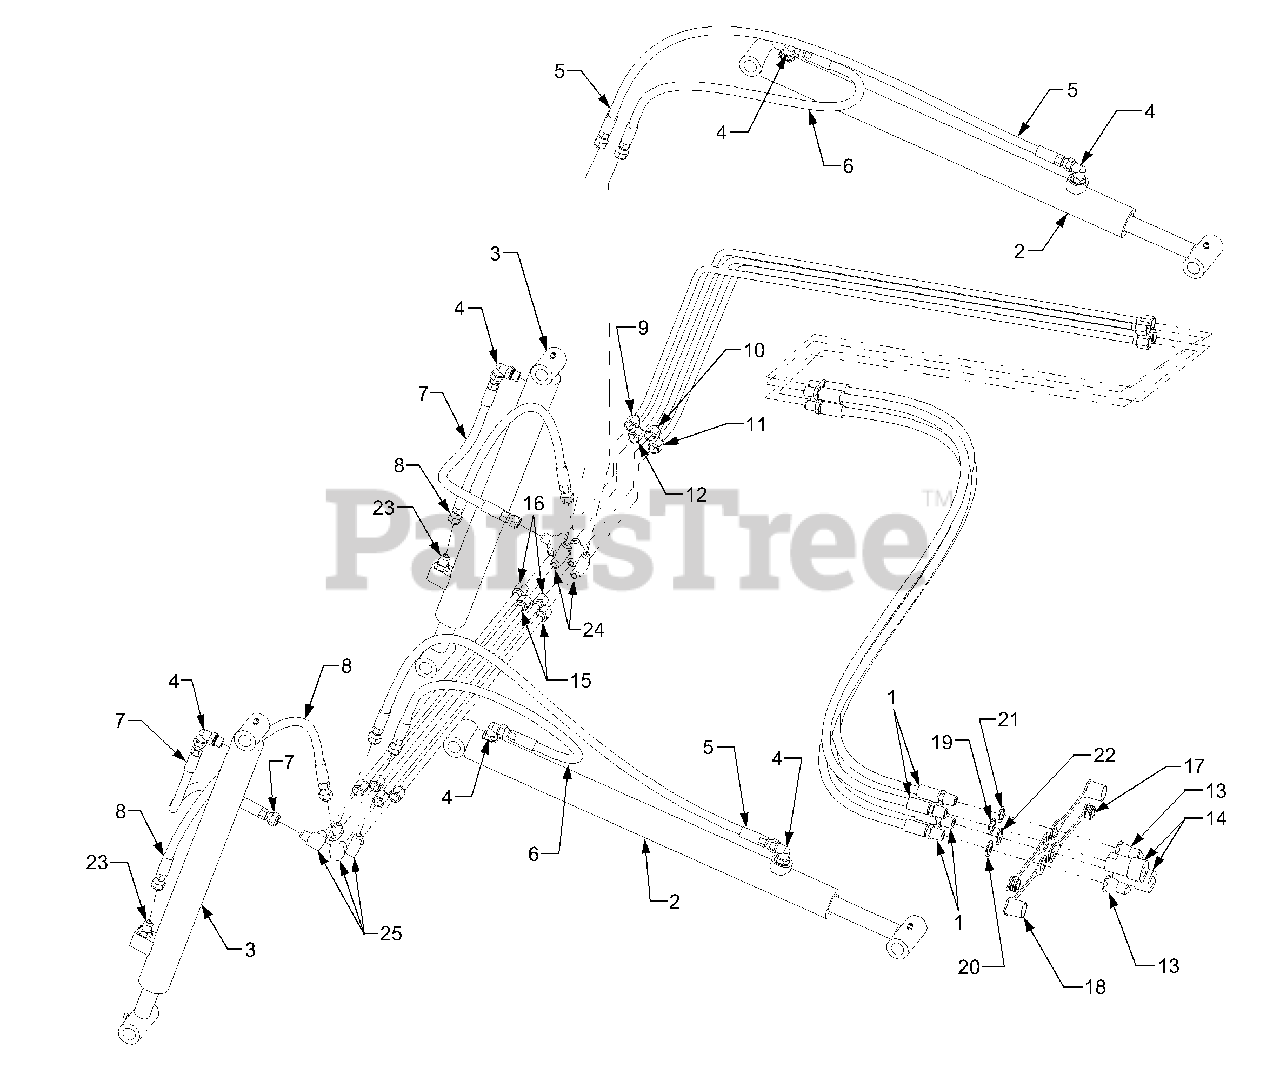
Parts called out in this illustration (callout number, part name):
1	Hose, Hydraulic, 3/8 ID
2	Cylinder, Loader Boom
3	Cylinder, Loader Bucket
4	Fitting, 90 Degree Orb.
5	Hose, Hydraulic, 3/8 ID
6	Hose, Hydraulic, 3/8 ID
7	Hose, Hydraulic, 3/8 ID
8	Hose, Hydraulic, 3/8 ID
9	Tube, Hydraulic
10	Tube, Hydraulic
11	Tube, Hydraulic
12	Tube, Hydraulic
13	Coupling, Hydraulic, 3/8-18 Male
14	Coupling, Hydraulic, 3/8-18 Female
15	Tube, Hydraulic
16	Tube, Hydraulic
17	Plug, Hydraulic Coupler, Male
18	Plug, Hydraulic Coupler, Female
19	Washer, Indicator, Red
20	Washer, Indicator, Yellow
21	Washer, Indicator, Green
22	Washer, Indicator, Blue
23	Fitting, Straight
24	Fitting, Union Tee
25	Fitting, Union Tee
